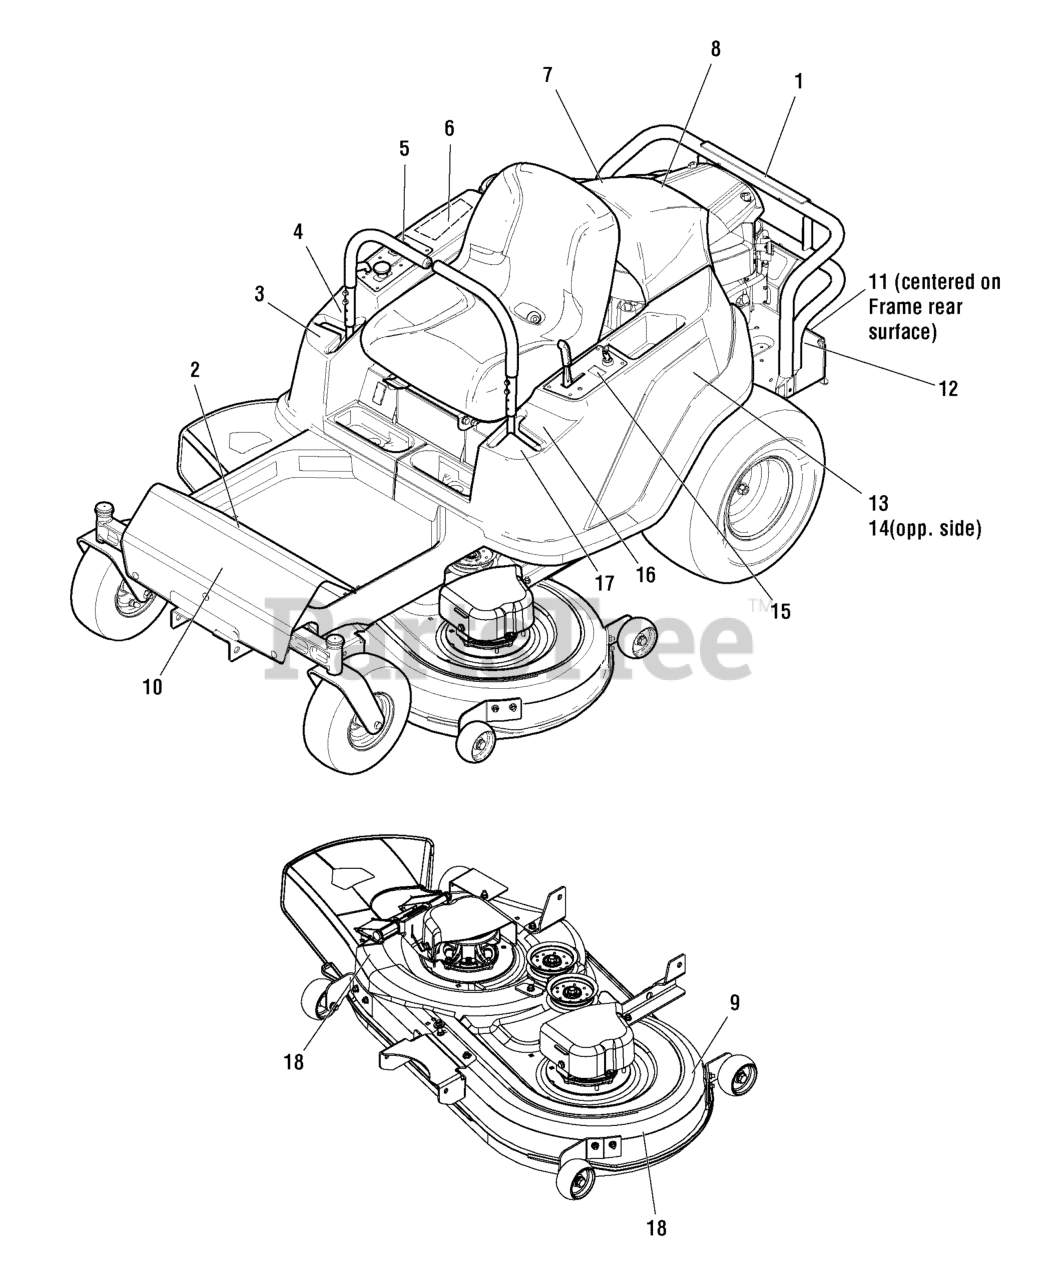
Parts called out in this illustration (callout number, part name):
1	DECAL, Rear, Craftsman ZTS
2	DECAL, Instructional, 285Z
3	DECAL, Handle, Ground Speed, RH, 285Z
4	DECAL, Safety, Symbol, 285Z
5	DECAL, Control Panel, RH 285Z
6	DECAL, DANGER, English, 285Z
7	DECAL, Release, Transaxle, 285Z
8	DECAL, Caution, Screen Rotating
9	DECAL, 42" Deck
10	DECAL, Model, Craftsman ZTS
11	DECAL, Weight Limitation
12	DECAL, Warning Burn Hazard
13	DECAL, LH Fender, Craftsman ZTS
14	DECAL, RH Fender, Craftsman ZTS
15	DECAL, Control Panel, LH 285Z
16	DECAL, WARNING, English, 285Z
17	DECAL, Handle, Ground Speed, LH, 285Z
18	DECAL, DANGER Do Not Operate w/o Deflector
19	DECAL, Engine/HP
